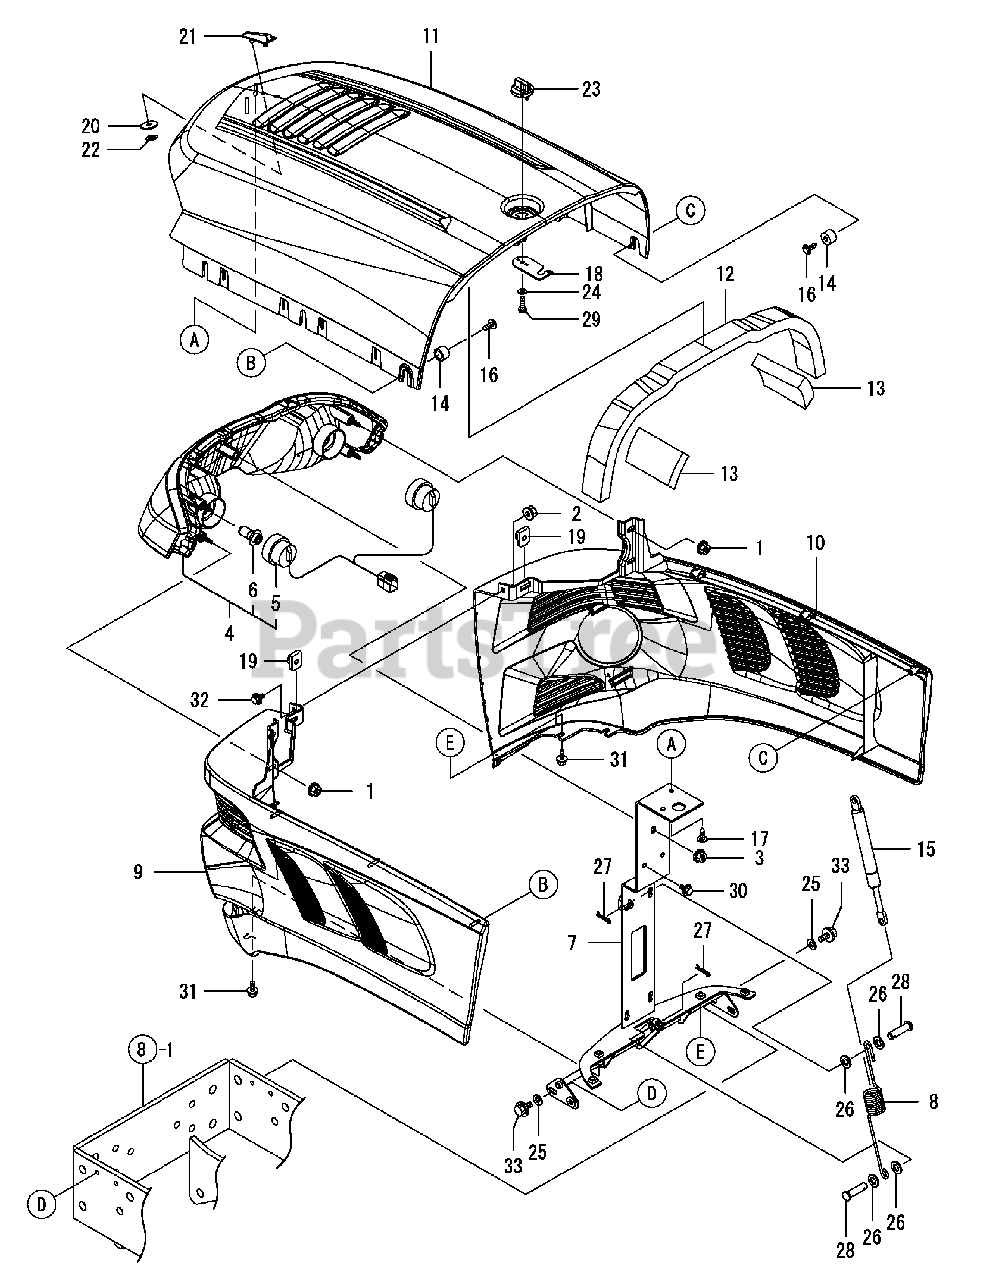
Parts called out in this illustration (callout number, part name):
1	NUT W/WASHER 6
2	NUT W/WASHER 6
3	NUT W/WASHER 6
4	LAMP ASSY, HEAD
5	WIRE, LEAD HEAD LAMP
6	BULB, HALOGEN12V30/30
7	HINGE CMP, HOOD
8	SPRING, HOOD HINGE
9	HOOD, LOWER LH
10	HOOD, LOWER RH
11	HOOD, UPPER
12	SEAL, HOOD UPPER
13	CUSHION, HOOD REAR
14	COLLAR, 10X15X10
23	KNOB, TOP SACKER
24	WASHER 5, POLISHED
25	WASHER 8, POLISHED
26	WASHER 8, POLISHED
27	SNAP PIN (JASO 8)
29	SCREW, 5.0 X 16
30	BOLT M 6X 16 PLATED
31	BOLT M 6X 16 PLATED
32	BOLT M 6X 16 PLATED
33	BOLT M 8X 16 PLATED
